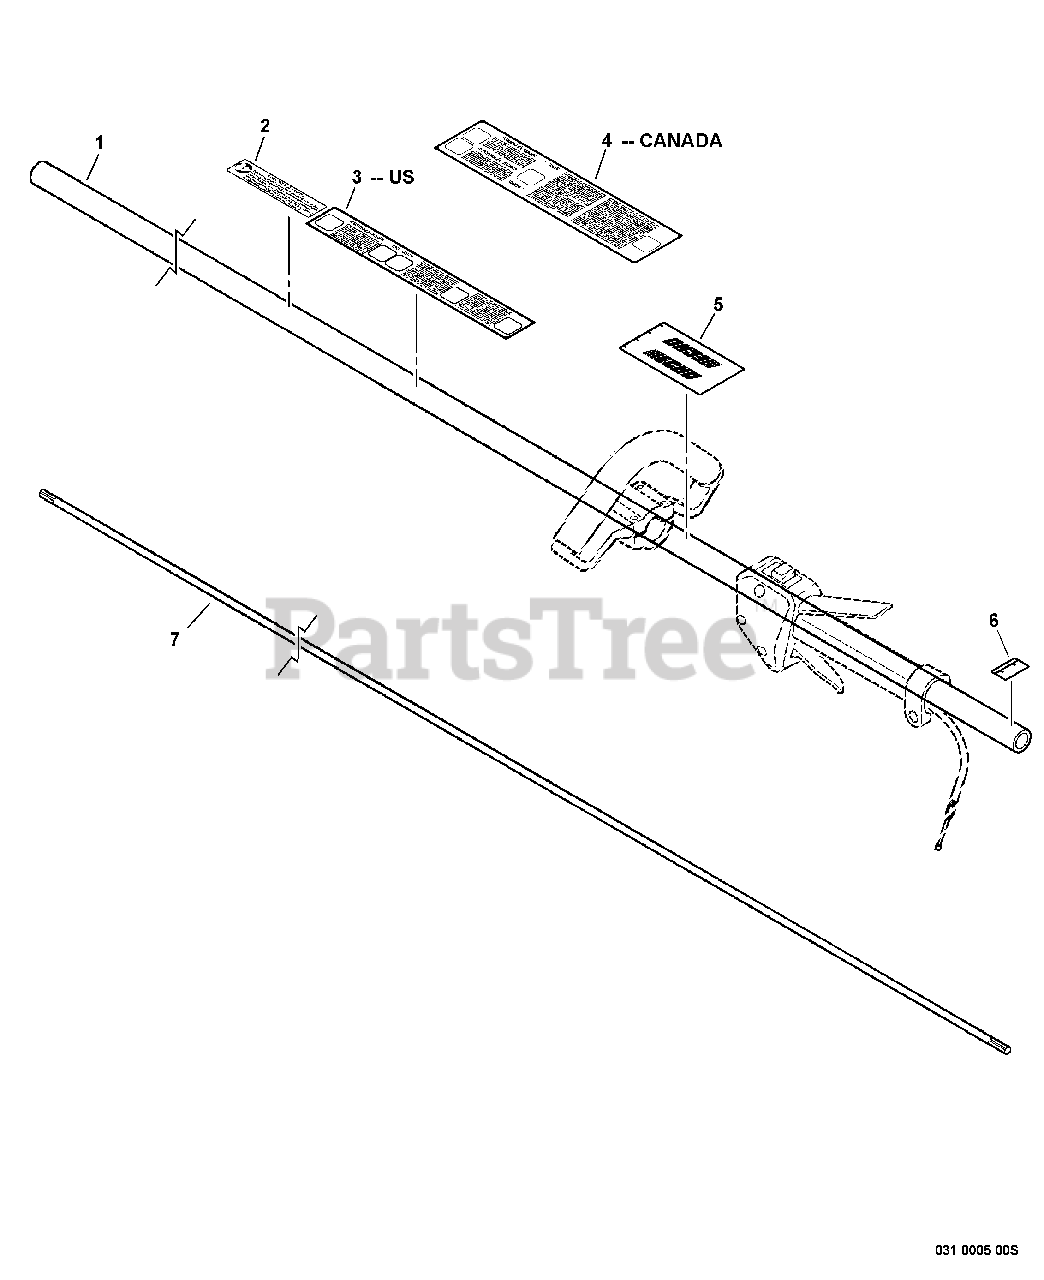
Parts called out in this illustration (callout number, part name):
1	MAIN PIPE ASSY
2	LABEL - CAUTION -- SPANISH
3	LABEL - CAUTION
4	LABEL - CAUTION
5	LABEL - HANDLE LOCATION
6	LABEL - ALIGNMENT
7	DRIVESHAFT - SOLID
